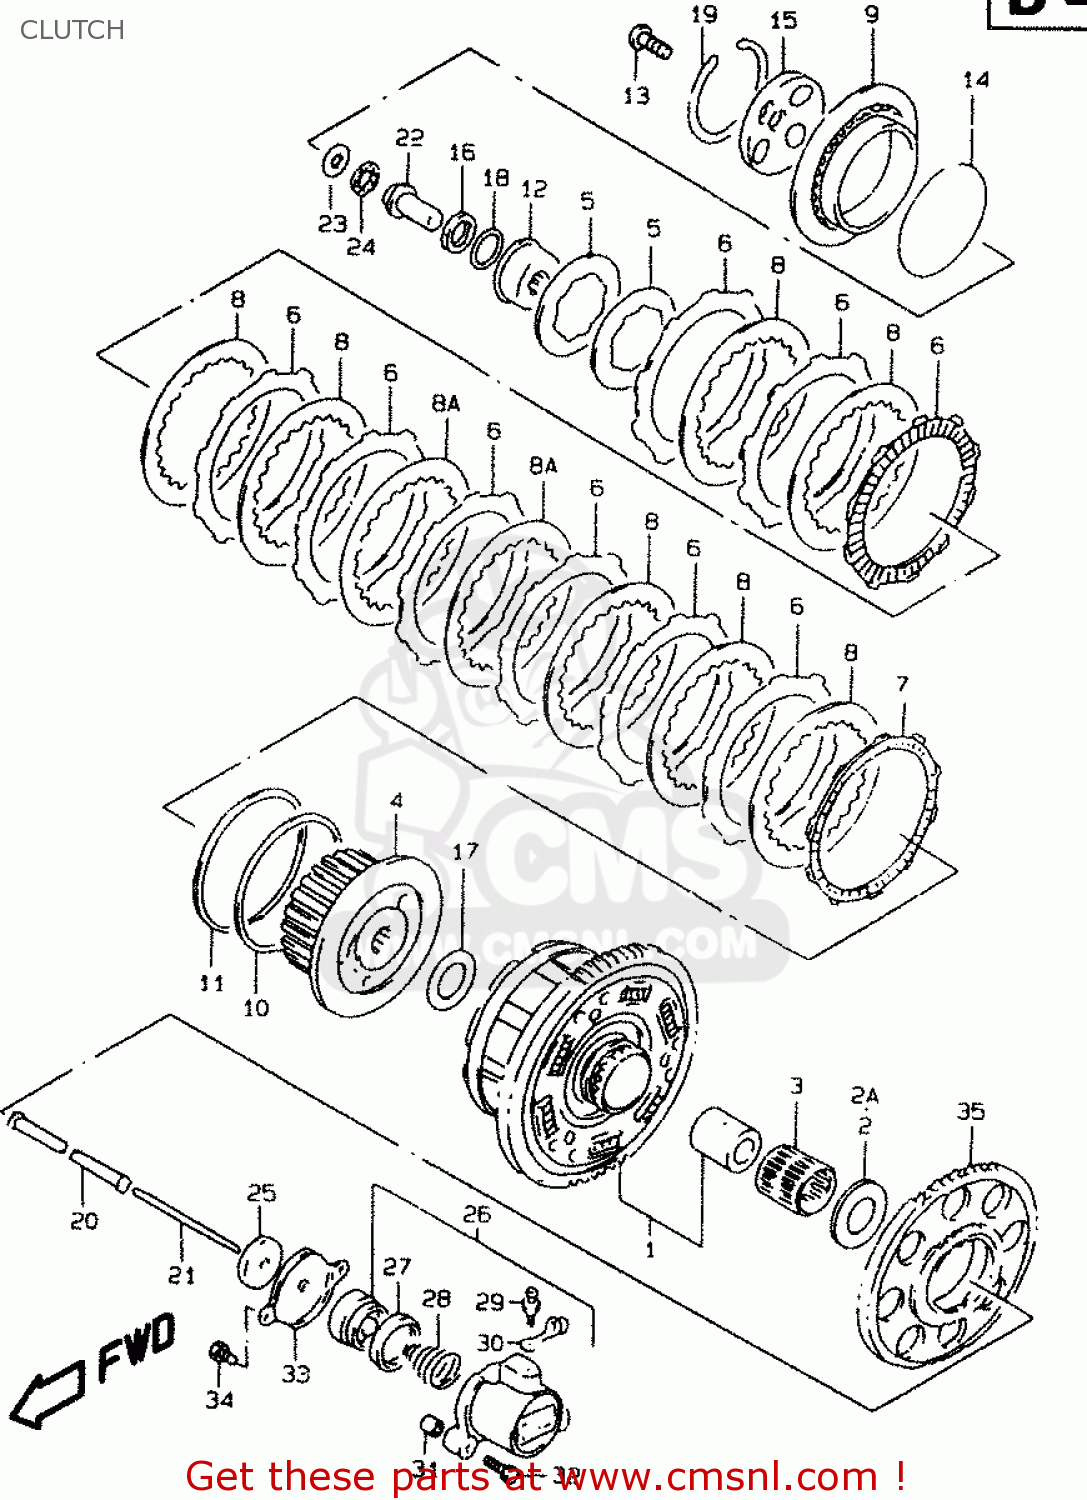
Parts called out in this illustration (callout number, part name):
1	GEAR ASSY,PRI DRIVEN
2	WASHER(25X54X2.5)
2A	WASHER(25X54X2.5)
3	BEARING(35X40X35.8)
4	HUB,CLUTCH SLEEVE
5	SPRING,CLUTCH
6	PLATE,CLUTCH DRIVE
7	PLATE,CLUTCH DRIVE
8	PLATE,CLUTCH DRIVEN NO.1
8A	PLATE,CLUTCH DRIVEN NO.2
9	DISC,CLUTCH PRESSURE
10	SEAT,CLUTCH PLATE WAVE WASHER
11	WASHER,CLUTCH PLATE WAVE
12	HOLDER,CLUTCH SPRING
13	SCREW,CLUTCH SPRING HOLDER
14	SEAT,CLUTCH SPRING
15	LIFTER,CLUTCH PRESSURE DISC
16	NUT
17	WASHER(25X50X2.5)
18	WASHER
19	CIRCLIP
20	ROD,CLUTCH PUSH,R
21	ROD,CLUTCH PUSH,L
22	PIECE,CLUTCH PUSH
23	WASHER(15.5X28X1)
24	BEARING(15X28X2)
25	SEAL,OIL(6X34X5.5)
26	CYLINDER,CLUTCH RELEASE
27	CUP
28	SPRING,CLUTCH CYLINDER
29	BLEEDER
30	CAP,BLEEDER
31	PIN
32	BOLT,CL.COVER
33	COVER,CLUTCH RELEASE CYLINDER
34	SCREW
35	GEAR,GENERATOR DRIVE
